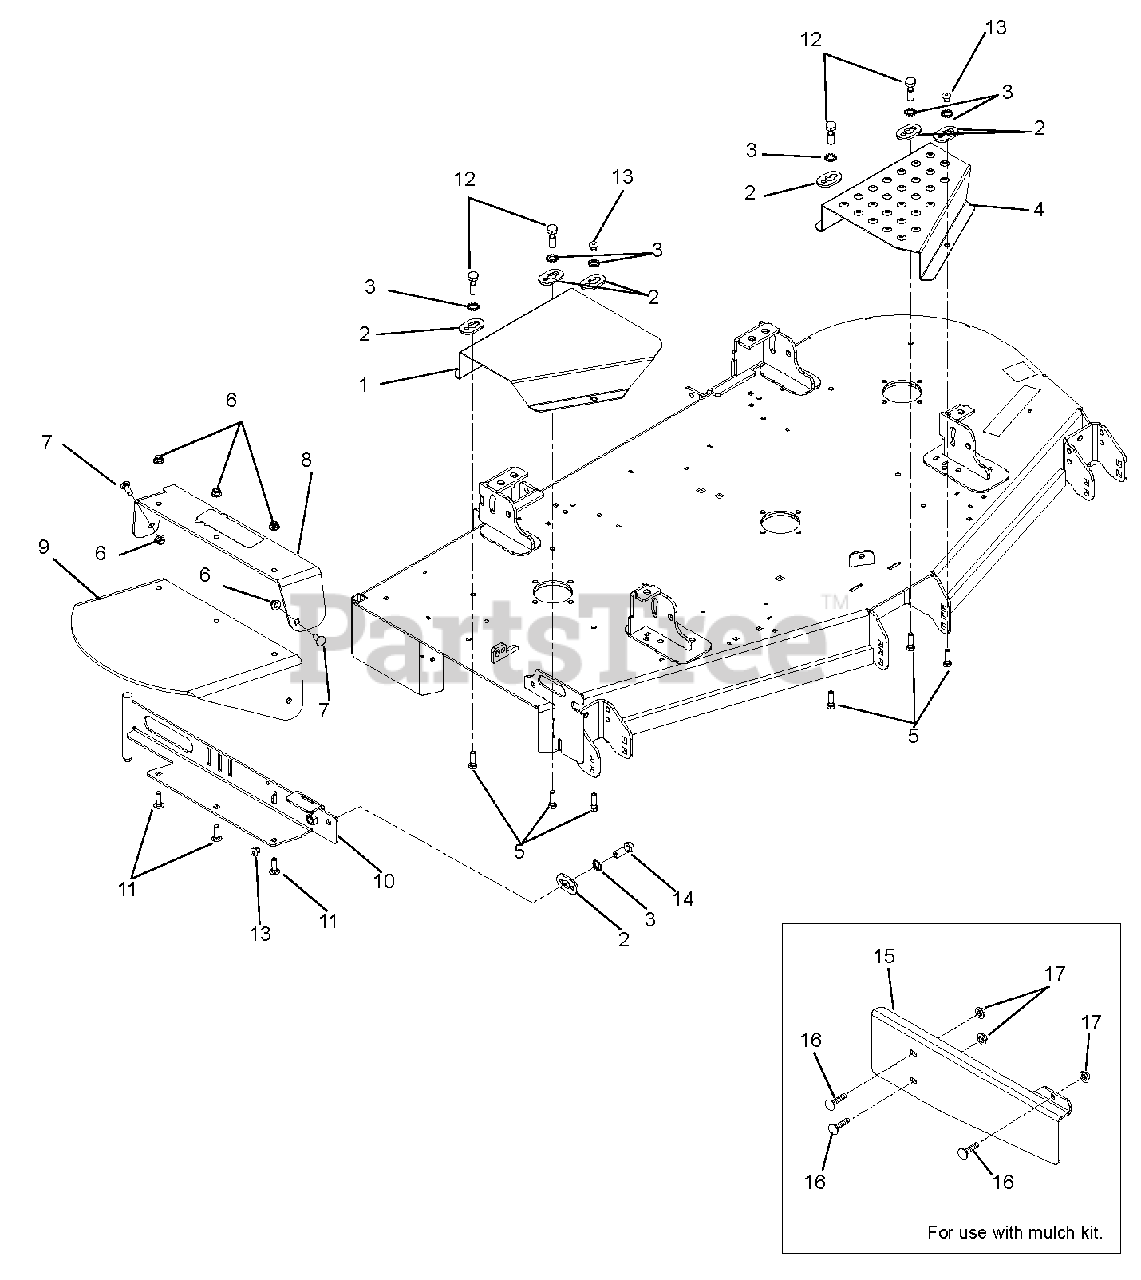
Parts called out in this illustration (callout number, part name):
1	Guard, Right Hand PT200 CE Belt
2	Keeper, Bolt
3	Washer, Locking Ext. .391 x .682 x .036
4	Guard, Left Hand PT200 CE Belt
5	Bolt, Hex .38-16 x 1.25 Grade 5
6	Nut, Locking Nylon Flange .38-16
7	Bolt, Round Head Square Neck .38-16 x 1.00 Grade 5
8	Support, Rubber Discharge Chute
9	Chute, Rubber Discharge
10	Weldment, 52" Discharge Chute Mounting, CE
11	Bolt, Round Head Square Neck .38-16 x 1.25 Grade 5
12	Bolt, Hex .38-16 x 1.25 Captive
13	Rivet, Pop .187 (IFI 114 Gr. 30)
14	Bolt, Hex .38-16 x 1.25 Cap .37
15	Cover-Discharge 52" CE
16	Bolt, Round Head Square Neck .31-18 x 1.00 Grade 5
17	Nut, Locking Nylon Flange .31-18
